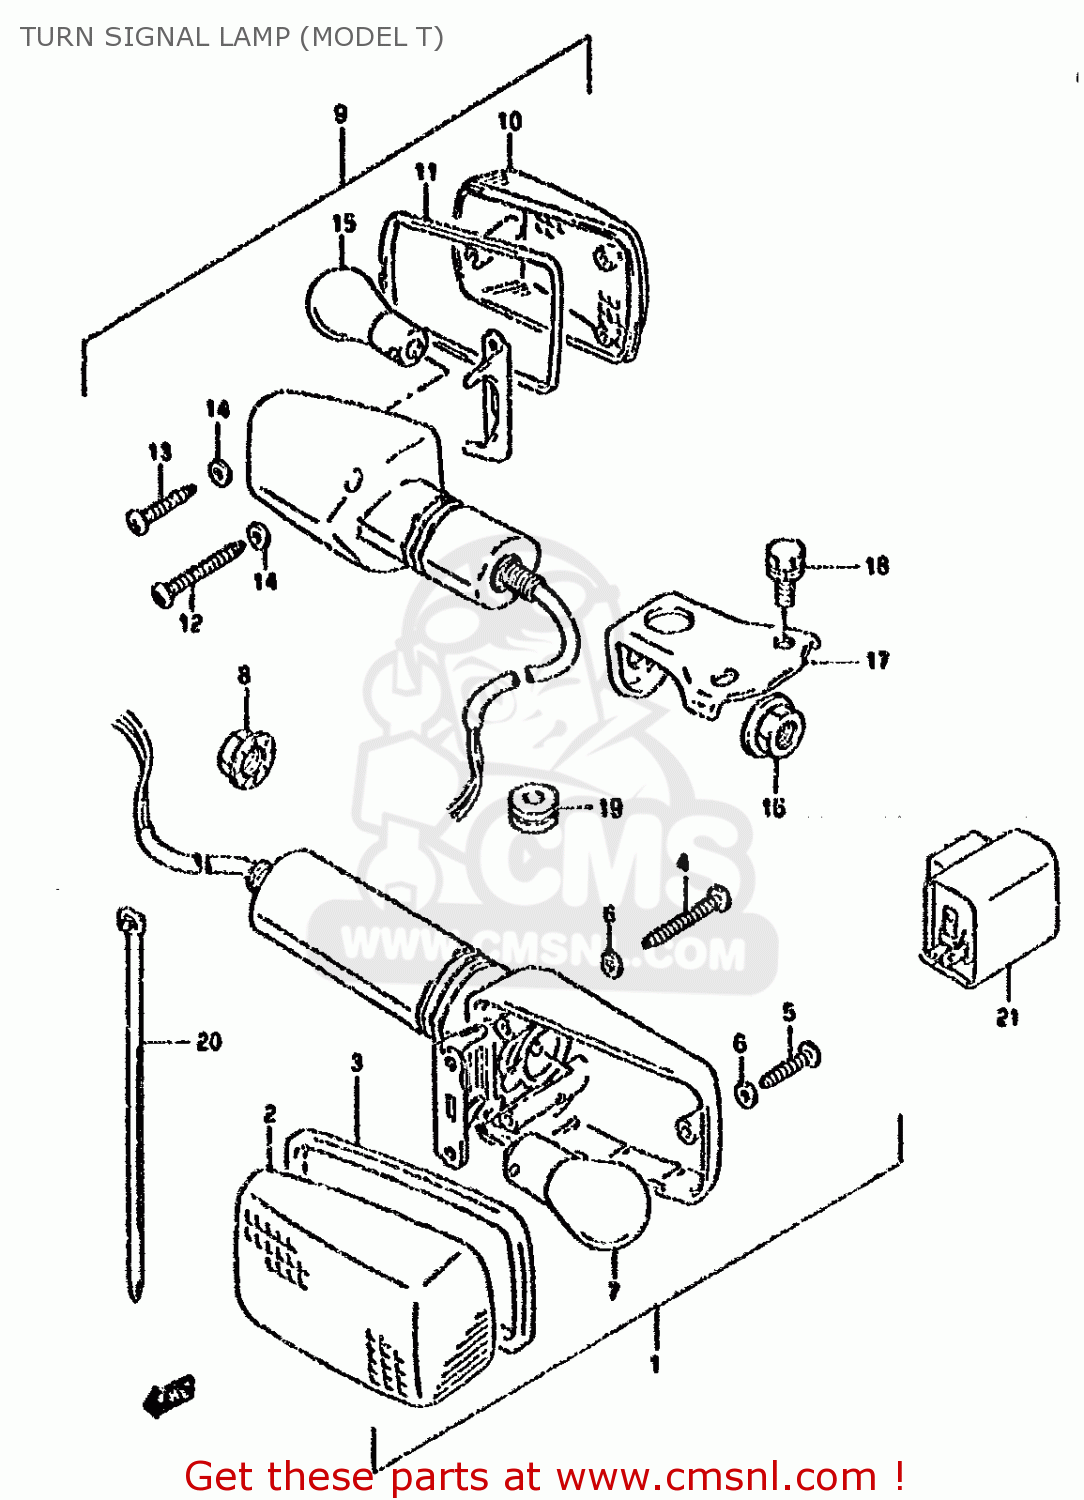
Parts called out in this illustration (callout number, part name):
1	LAMP ASSY,FR TURN SIGNAL
2	LENS
3	GASKET (NAS)
4	SCREW(3X30)
5	SCREW
6	GASKET (NAS)
7	BULB(12V21W)
8	NUT
9	LAMP ASSY,RR TURNSIGNAL,R
10	LENS
11	GASKET (NAS)
12	SCREW(3X30)
13	SCREW
14	GASKET (NAS)
15	BULB(12V21W)
16	NUT
17	BRACKET,RR TURNSIGNAL
18	BOLT
19	GROMMET
20	CLAMP(L:45)
21	GROMMET
22	CLAMP
23	RELAY ASSY,TURNSIGNAL LAMP
